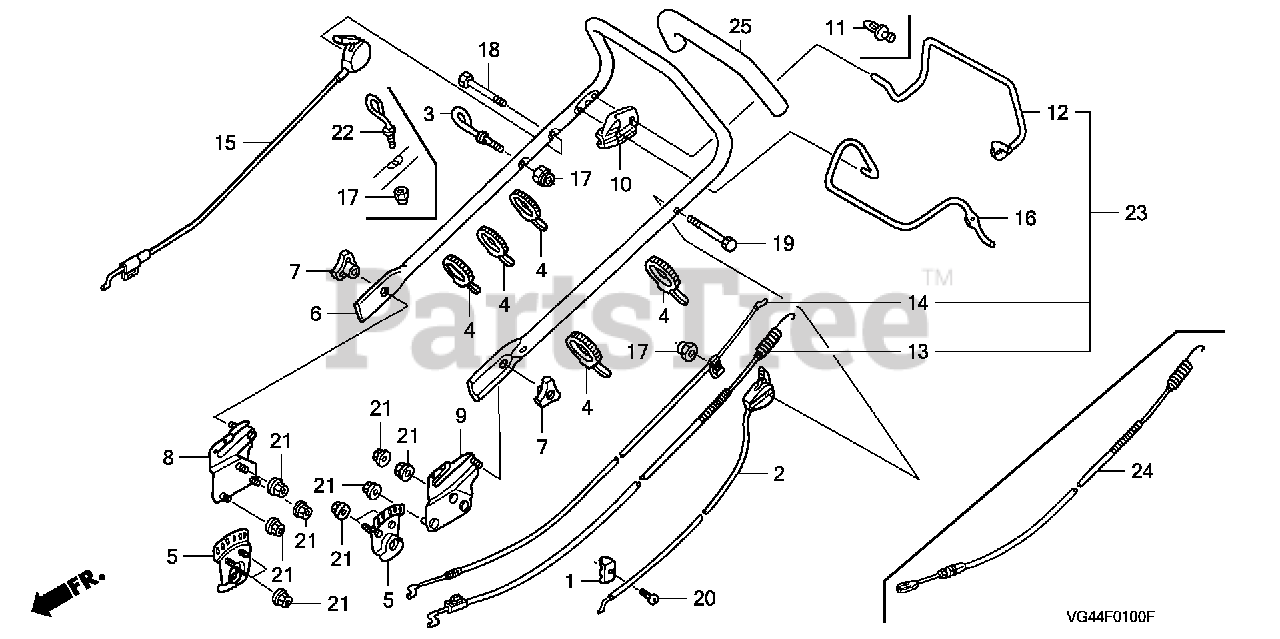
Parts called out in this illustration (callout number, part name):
1	HOLDER, CABLE
2	LEVER ASSY., THROTTLE
4	TIE, CABLE (157.5MM)
5	PANEL, RR. ADJUSTER
6	PIPE, HANDLE *NH105* (MAT BLACK)
7	GRIP, HANDLE JOINT
8	STAY, R. HANDLE
9	STAY, L. HANDLE
10	STOPPER, LEVER
14	CABLE, BRAKE
16	LEVER, BRAKE
17	NUT, NYLON LOCK (6MM)
19	BOLT, HEX. (6X60)
20	SCREW, PAN (5X16)
21	NUT, FLANGE (8MM)
22	GUIDE, ROPE
